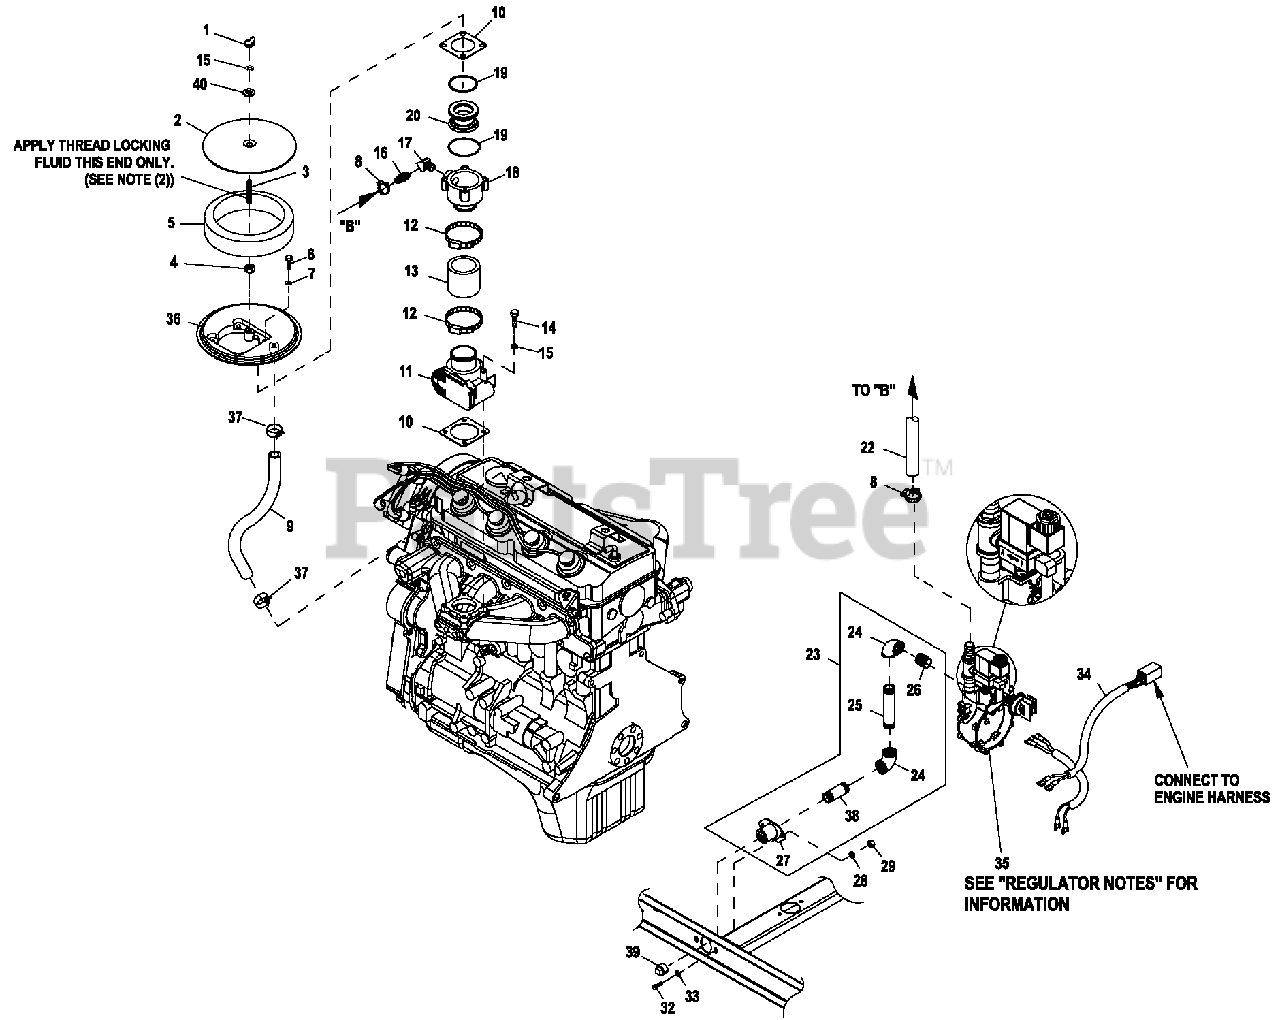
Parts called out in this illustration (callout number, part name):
1	NUT WING 1/4-20
2	COVER AIR CLEANER
3	STUD TH 1/4-20 X 3 G2 ZNC FULL
4	NUT HEX 1/4-20 STEEL
5	FILTER ELEMENT
6	SCREW PPHM M5-0.8 X 12 ZNC
7	WASHER LOCK M5
8	CLAMP HOSE #10 .56-1.06
9	HOSE 3/8 ID SINGLE BRAID (15" LG)
10	GASKET BOSCH 32
11	ACTUATOR BOSCH 32 GOVERNOR
12	CLAMP HOSE #28 1.32-2.25
13	HOSE 1.5 ID X 2 LG 20R4
14	SCREW HHC M6-1.0 X 45 C8.8 FTH
15	WASHER LOCK M6-1/4
16	BARBED STR 1/2 NPT X 3/4
17	STREET EL 45D 1/2 NPT BRASS
18	MIXER ACTUATOR 32MM MACHINED
19	O-RING 47.625 ID X 2.38 WIDTH
20	VENTURI THROTTLE 19MM
22	HOSE 3/4 ID SAE-30R2 (18" LG)
23	ASSY REG INLET NPT FITTINGS
24	ELBOW 90D 3/4 NPT
25	NIPPLE PIPE 3/4NPTX4.5 BLK IRN
26	NIPPLE CLOSE 3/4X1.375
27	FLANGE FUEL INLET
28	WASHER LOCK M8-5/16
29	NUT HEX M8-1.25 G8 YEL CHR
32	SCREW HHC M8-1.25 X 20 G8.8
33	WASHER FLAT 5/16 ZINC
34	HARN FUEL JUMPER SINGLE REG
35	FUEL REG REWORK 2.4 1800 22/27
36	ADAPTER, CARBURETOR W/PCV CONN
37	CLAMP HOSE BAND .63
38	NIPPLE PIPE 3/4NPT X 2
39	PLUG STD PIPE 3/4 STEEL SQ HD
40	WASHER FLAT 1/4-M6 ZINC
